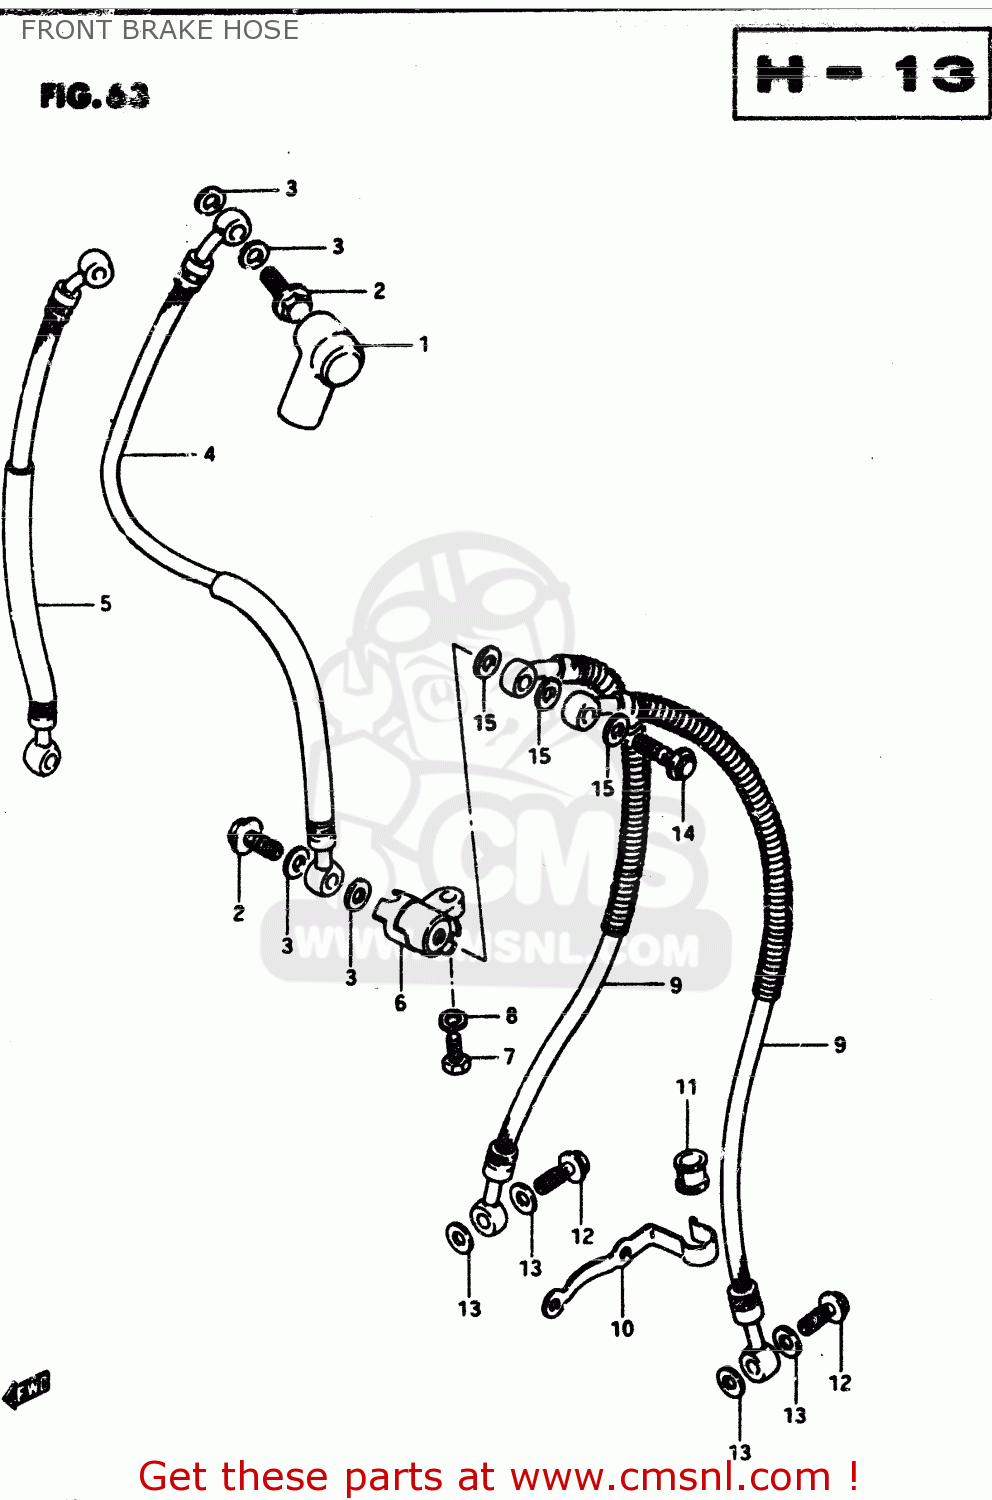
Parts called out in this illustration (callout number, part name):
1	BOOT,MASTER CYLINDER
2	BOLT,UNION
3	WASHER
4	HOSE,BRAKE NO.1
5	HOSE, BRAKE NO.1 (L:390)
6	JOINT,BRAKE HOSE
7	BOLT
8	LOCK WASHER
9	HOSE,FRONT BRAKE
10	GUIDE,BRAKE HOSE NO.2
11	BUSH,BRAKE HOSE GUIDE,NO.2
12	BOLT,UNION
13	WASHER
14	BOLT,UNION
15	WASHER
